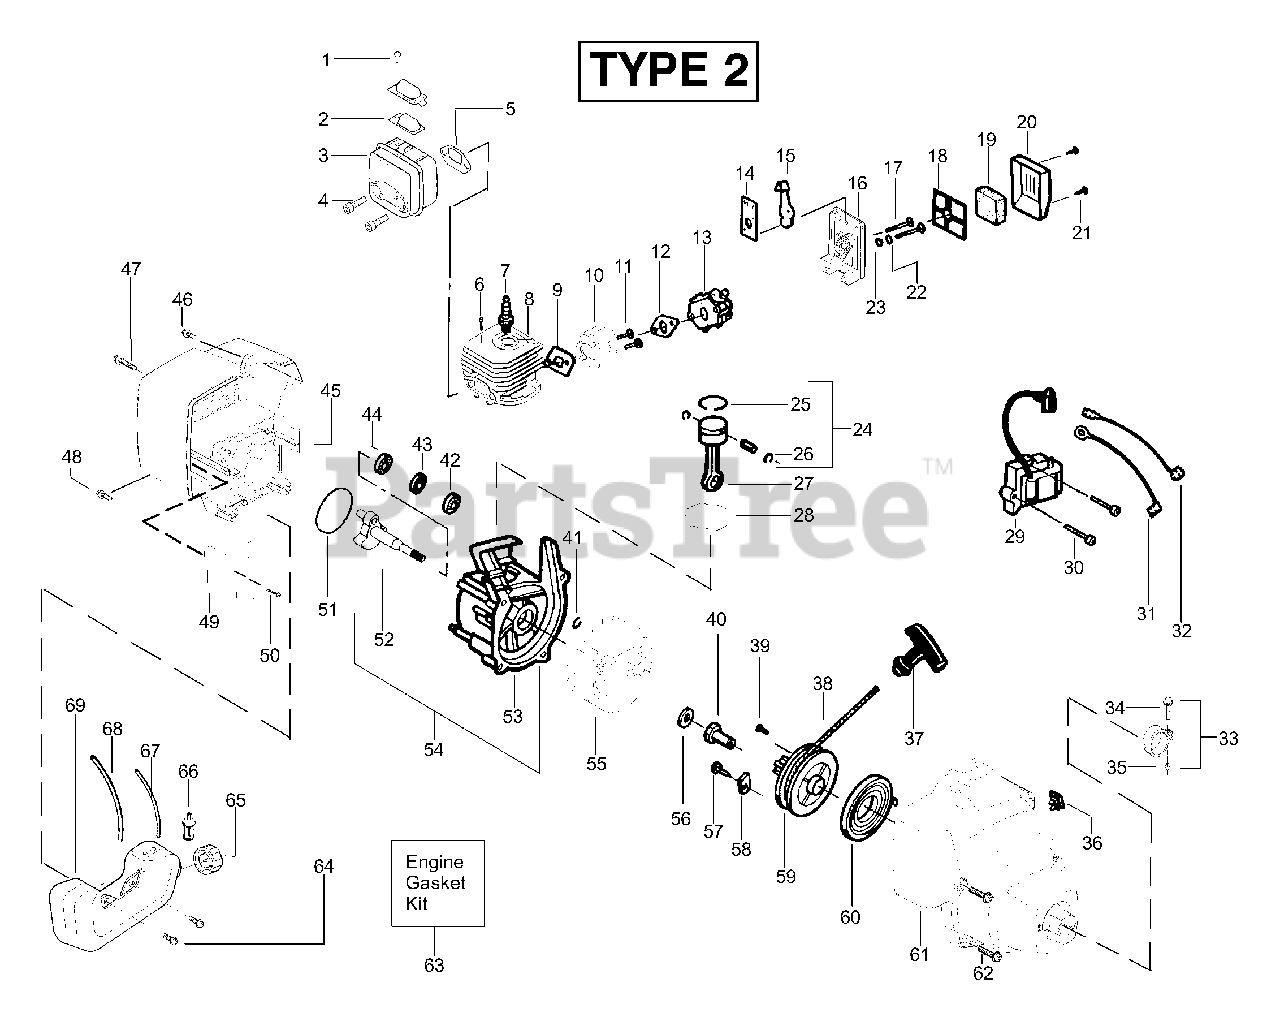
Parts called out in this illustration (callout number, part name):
1	Screw-Screen
2	Kit-Spark Arrestor
3	Kit-Muffler
4	Bolt-Muffler
5	Gasket-Muffler (kit)
6	Screw-Cylinder
7	Spark Plug (RCJ 6Y)
8	Kit - Cylinder
9	Gasket-Cyl./Carb.(kit)
10	Adapter-Carb.
12	Gasket-Carb. (kit)
13	Kit-Carb.(C1Q-W10B)
14	Choke Plate Mounting
15	Shutter-Choke
18	Plate - Filter Support
19	Foam-Air Filter
20	Cover-Air Filter
22	Spacer-Choke
24	Kit - Piston
25	Piston Ring
26	Retainer-Piston Pin
27	Assy-Connecting Rod
28	Seal-Cylinder (kit)
29	Ignition Module
31	Assy-Ground Wire
32	Assy-Leadwire
33	Assy-Nose Cone Clamp
34	Screw-Nose Cone
35	Nut-Nose Cone
36	Kit-On/Off Switch
37	Handle-Starter
38	Kit - Rope
40	Coupling-Drive
41	Retain. Ring-C'shaft
42	Outer Bearing
43	Kit-C'case Seal
44	Inner Bearing
45	Shroud-Rear
47	Screw
49	Shield-Heat
50	Screw
51	O-Ring-C'case (kit)
52	Assy-Crankshaft
53	Assy-Crankcase
54	Assy-C'case & C'shaft
55	Assy-Flywheel
56	Washer-Flat
58	Retainer-Can
59	Kit-Starter Pulley
60	Spring-Starter
61	Assy.-Fan Hsg
62	Screw
63	Kit-Engine Gasket
65	Assy-Fuel Cap
66	Assy-Fuel Pickup
67	Kit-Fuel Line (Small)
68	Kit-Fuel Line (Large)
69	Assy-Fuel Tank
